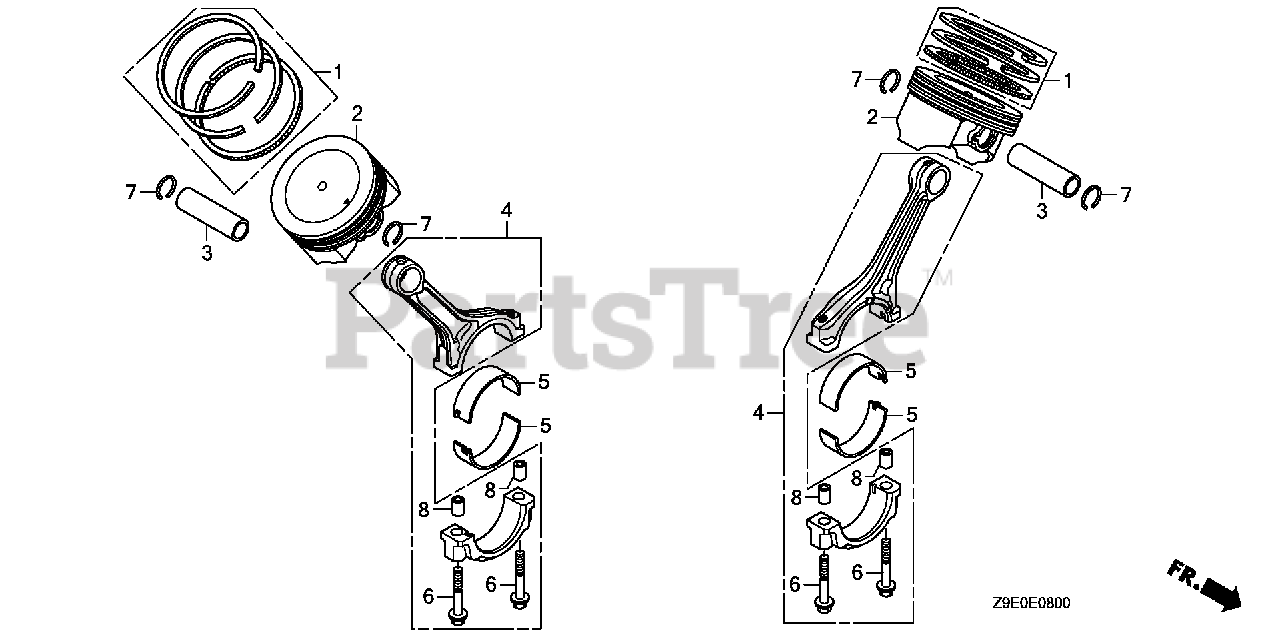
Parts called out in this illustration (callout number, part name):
1	RING SET, PISTON (STD.) (TEIKOKU)
2	PISTON
3	PIN, PISTON
4	ROD ASSY., CONNECTING
5	BEARING A, CONNECTING ROD
6	BOLT, CONNECTING ROD (7X38)
7	CLIP, PISTON PIN (18MM)
8	PIN, DOWEL (9X10)
